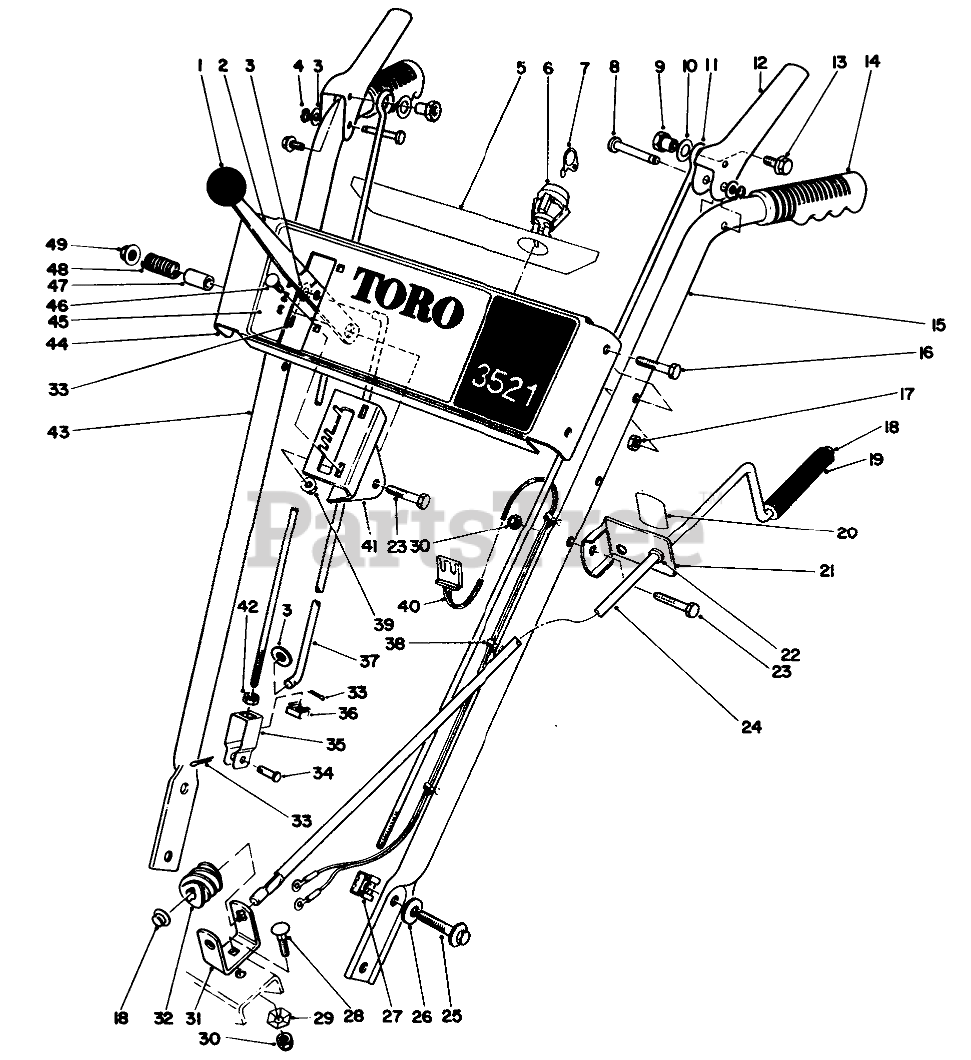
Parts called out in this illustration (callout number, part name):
2	SPEED SELECTOR B
3	WASHER-PLAIN
4	RING-CLIP
5	Decal-Escutcheon Back
6	SWITCH
7	KEY-IGNITION
8	PIN-LEVER, CONTROL
9	POST-MOUNTING, LINKAGE
10	WASHER-FLAT
11	LINK-UPPER
12	HANDLE-CONTROL
13	SCREW-HHF
14	Grip
15	LEFT HANDLE
16	SCREW-HH
17	NUT-LOCK, CONE
18	RETAINER-PUSH ON
19	GRIP-CONTROL, CHUTE
20	DECAL-CHUTE DIRECTION
21	Bracket-Chute Control (Incl. Ref. #20 & 22)
22	Bushing
23	SCREW-HH
24	ROD-CONTROL, CHUTE
25	SCREW-HH
26	WASHER-BELLEVILLE
28	BOLT-CARR
29	WASHER-LOCK
30	NUT-LOCK, NI
31	BRACKET-WORM
32	GEAR-WORM, CHUTE
33	PIN-COTTER
34	PIN-CLEVIS
35	CLEVIS
36	NUT-RETAINED
37	ROD-SELECTOR, SPEED
38	Mount-Wire
39	NUT-HHF
40	Wire Harness Assembly (Incl. Ref. #38)
41	Mount-Speed Selector
42	NUT-JAM
43	RIGHT HANDLE
44	ESCUTCHEON PLT B
45	Decal-3521
46	SCREW-CARRIAGE
47	SPACER
48	SPRING
49	NUT-HF
